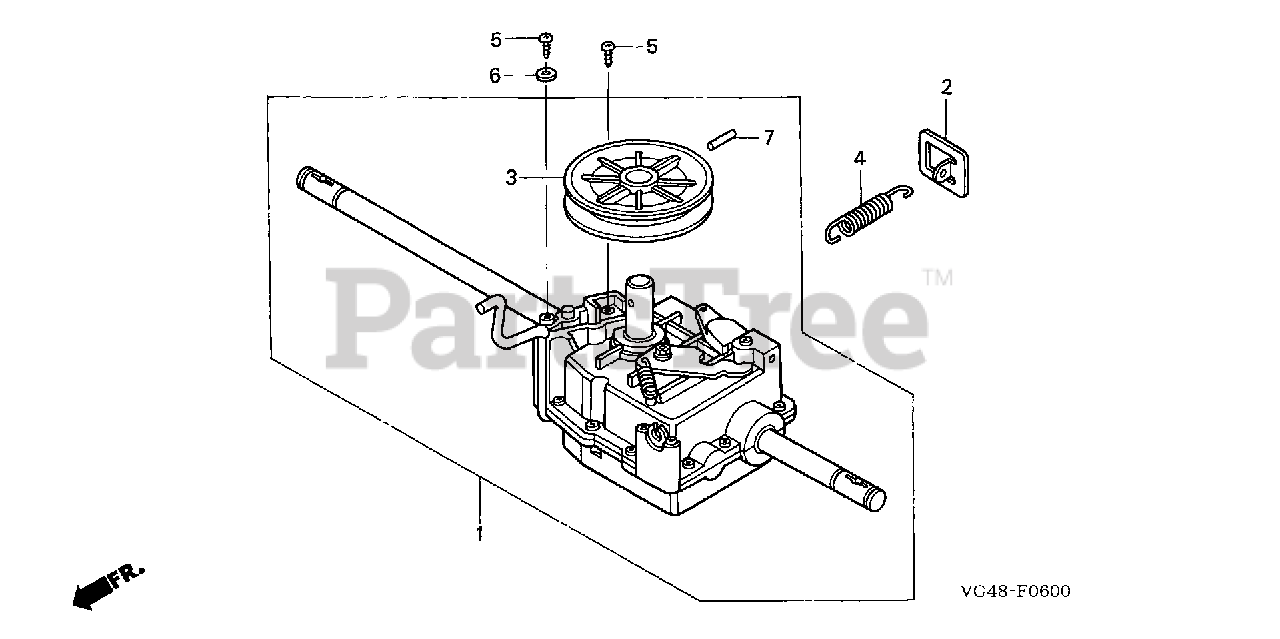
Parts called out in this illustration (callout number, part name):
1	TRANSMISSION ASSY.
2	PLATE, TENSION SPRING
3	PULLEY, DRIVEN
4	SPRING, WHEEL TENSION
5	SCREW, TAPPING (5X12) (PO)
6	WASHER, PLAIN (6MM)
7	PIN, SPRING (5X36)
